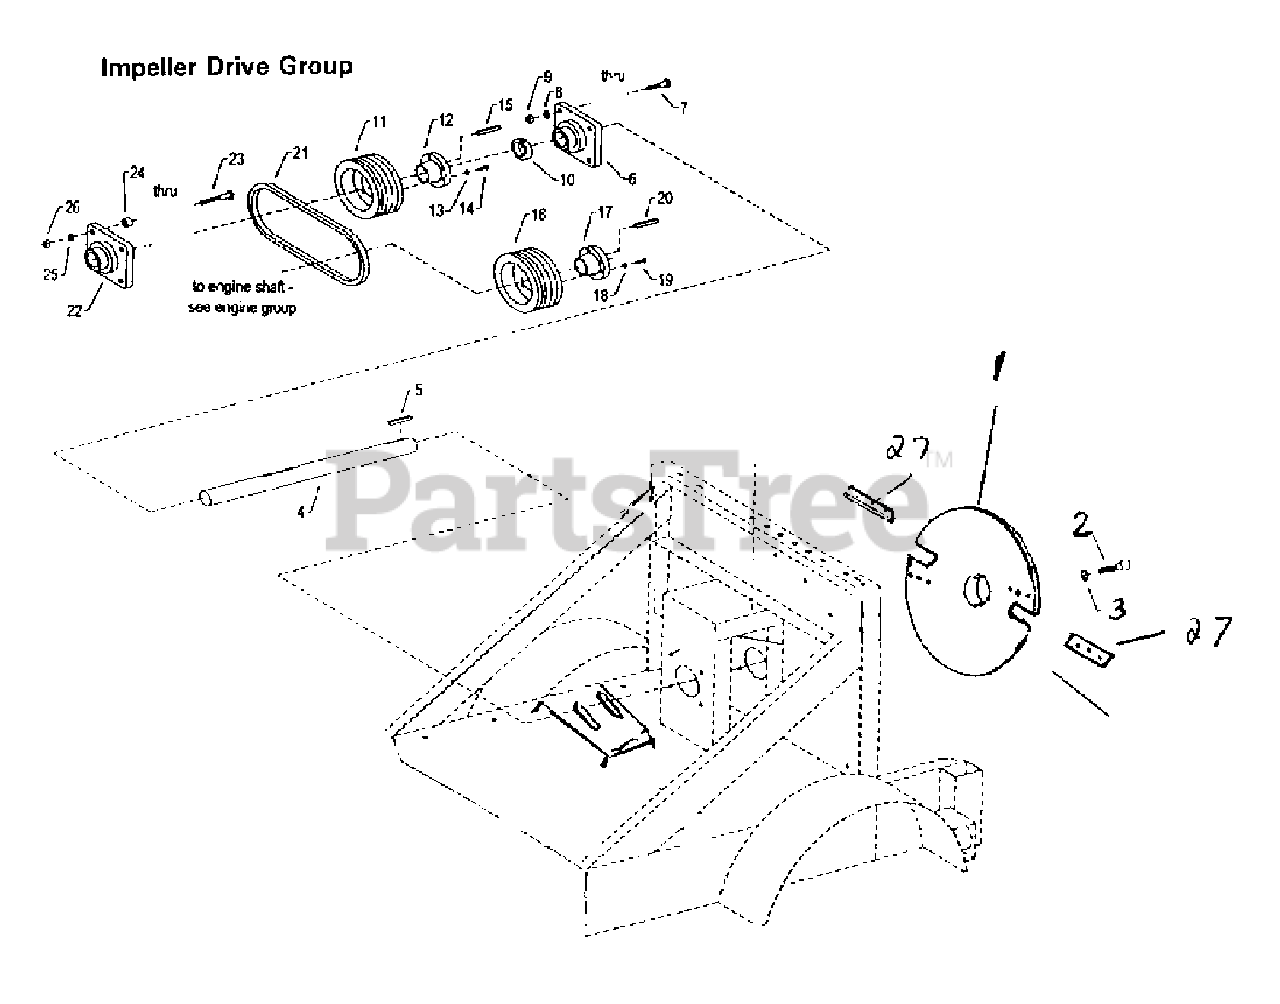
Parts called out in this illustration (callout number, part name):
2	Impeller Bolt & Key Set
3	5/8 Lock Washer
4	Impeller Shaft
5	Key
6	Bearing 1-7/16
7	1/2x13 x 1-1/2 Bolt
8	1/2 Lock Washer
10	Single Split Collar 1-7/16
11	Pulley
12	Bushing 1-7/16
13	3/8 Lock Washer
14	3/8-16 x 1-1/2 Bolt
16	Pulley
17	Bushing 1-7/16
18	3/8 Lock Washer
19	3/8-16 x 1-1/2 Bolt
21	Belt 3VX530-4
22	Bearing 1-7/16
23	1/2-13 x 2 Bolt
25	1/2 Lock Washer
27	Chipper Blade
